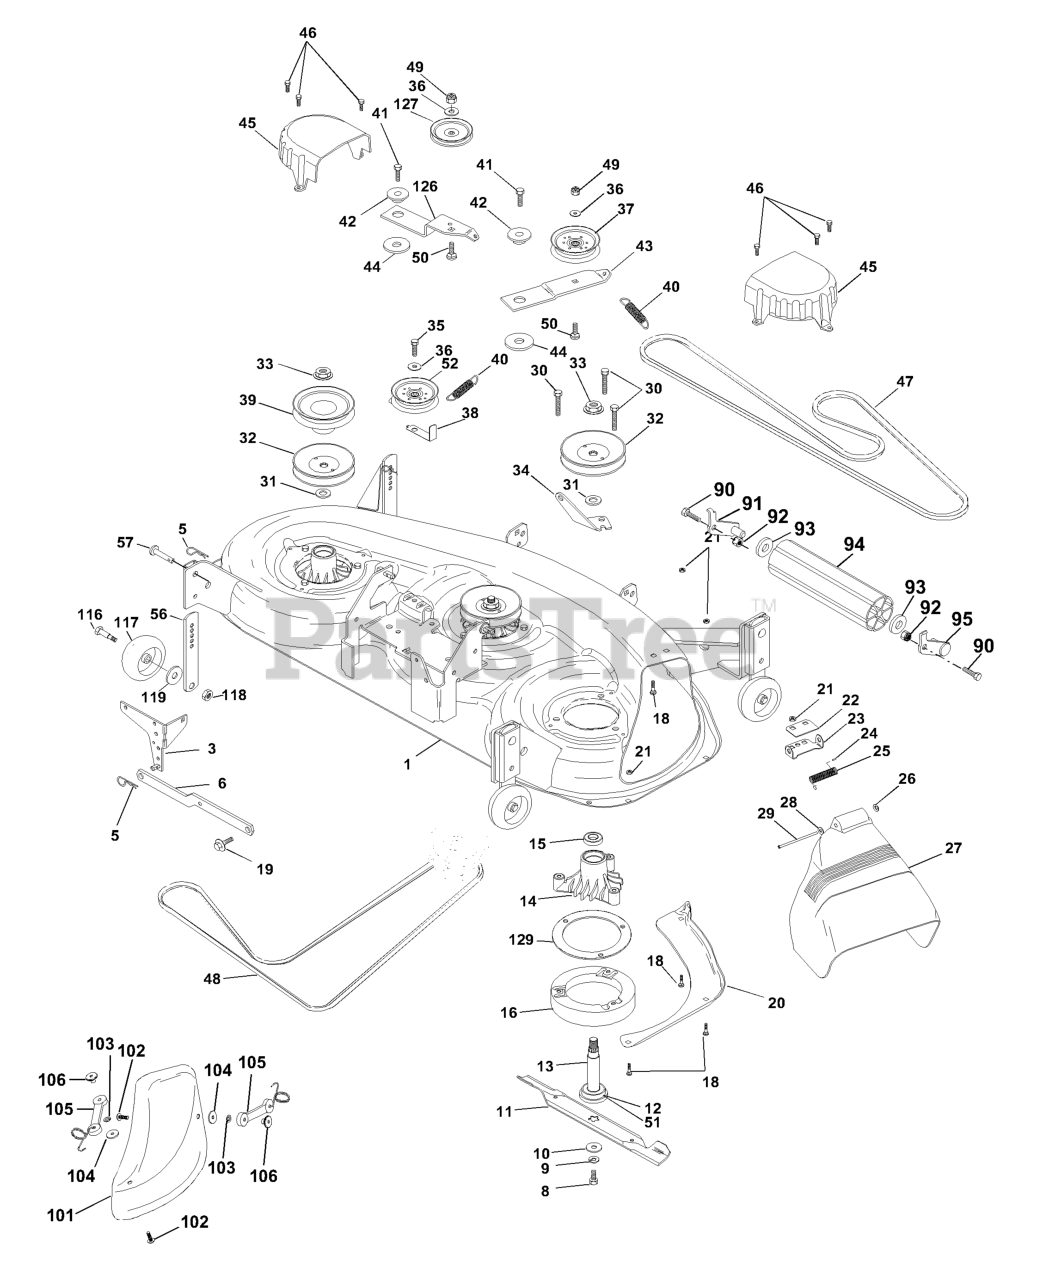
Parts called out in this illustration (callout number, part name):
1	DECK
3	BRACKET SWAY BAR
5	RETAINER SPRING
6	REAR SUSP ARM
8	BLADE BOLT
9	WASHER LOCK
10	WASHER.BLADE
11	46" HIGH PERFORMANCE BLADE
11	MULCH BLADE 46"
12	BEARING.BALL.#6204.(MANDREL)
13	SHAFT.ASM.W/BEARING
14	HOUSING.MANDREL.44/46" VENT
16	STRIPPER
18	Bolt, Carriage 5/16-18 x 5/8
19	BOLT
20	BAFFLE, VORTEX MOWER 46"
21	NUT
22	STIFFENER BRACKET
23	DEFLECTOR BRACKET
24	CAP-SLEEVE LT
25	TORSION SPRING
26	NUT PUSH M
27	SHIELD DEFLECTOR
28	WASHER
29	Rod, Hinge
30	SCREW
31	Washer, Spacer Mower Vented
32	PULLEY, MANDREL
33	NUT
34	ANCHOR, SPRING DECK 46"
35	SCREW
36	WASHER
37	FLAT IDLER PULLEY
38	KEEPER.BELT.IDLER
39	PULLEY.DRIVEN.DECK.46"
40	SPRING.SEC.44"VEN
41	SCREW
42	SPACER.RETAINER.MOWER
43	ARM IDLER DECK 46"
44	HARDENED WASHER
45	COVER MANDREL 46
46	SCREW
47	BELT V SECONDARY
48	V-BELT PRIMARY 50"
49	NUT
50	BOLT
51	WASHER FELT
52	PULLEY IDLER FLAT 46 PRI DRIVE
56	BAR.ADJUST.WHEEL.ANTI.SCALP.BL
57	PIN HEAD RIVET
72	Washer 13/32 x 1 x 16 Ga.
90	BOLT HEX FIN 3/8-13 X 1
91	BRACKET LH (A)
92	NUT
93	WASHER 17/32 X 7/8 X 16 GA.
94	NOSE ROLLER
95	BRACKET RH (B)
101	COVER.MULCH.46"3-BLADE.(2 2)
102	SCREW
103	LOCKWASHER #10
104	WELDNUT
106	LATCH ASSY
116	BOLT
117	WHEEL GAGE DONUT
118	NUT
119	BOLT
126	ARM IDLER PRIM 46
127	PULLEY.IDLER.4.25
129	Reinforcement Mandrell Ring
